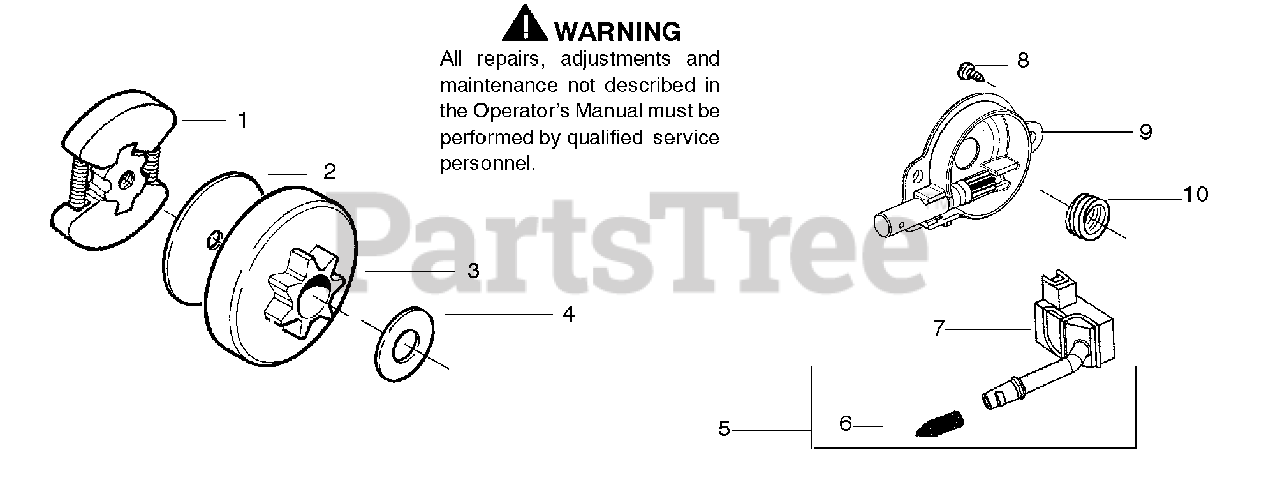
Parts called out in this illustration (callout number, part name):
1	Assy-Clutch
2	Washer-Clutch
3	Assy-Clutch Drum w/Bearing
4	Washer-Thrust
5	Assy-Oil pickup and screen
6	Filter-Oil
7	Assy-Pickup
9	Assy-Oil Pump
10	Worm Gear-Oil Pump
